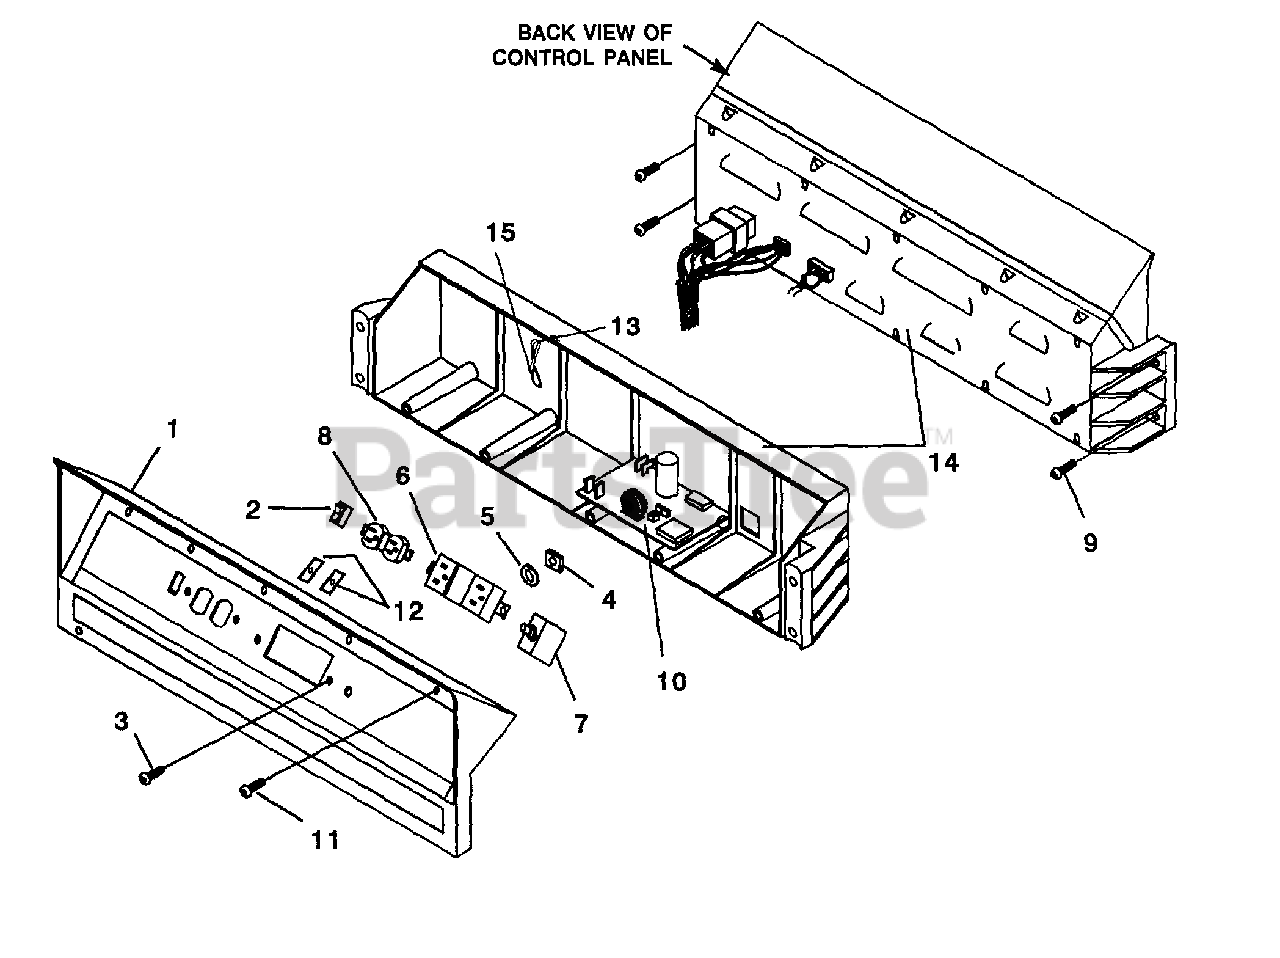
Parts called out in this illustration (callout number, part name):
1	Control Panel
2	Switch
3	Screw - Pan Hd. (8-32 X 7/8")
4	Nut - Hex
5	Washer - Lock
6	Receptacle (GFCI)
7	Circuit Breaker (20 amp)
8	Receptacle - Duplex (120 V)
9	Screw - Torx Hd. (10-24 X 1/2")
10	Control Board
11	Screw - Thread Forming (8-16 X 3/4")
12	Bumper - Rubber
13	Tie - Cable
14	Control Panel - Back
15	Clip, Tie
